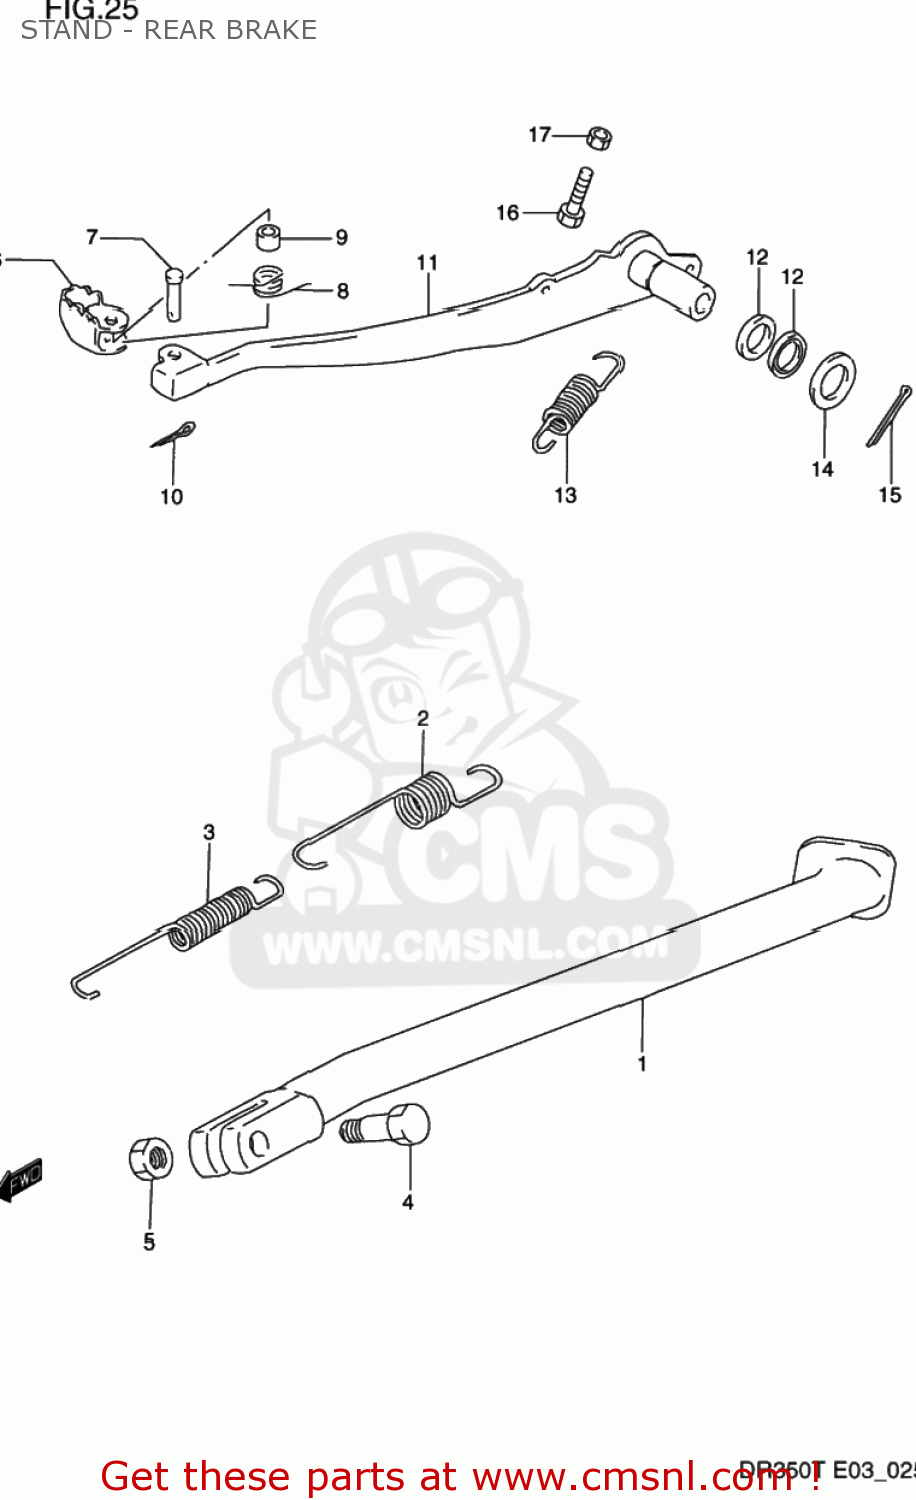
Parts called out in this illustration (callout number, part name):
1	STAND,SIDE
2	SPRING
3	SPRING
4	BOLT(10X30)
5	NUT
6	PEDAL,BRAKE
7	PIN
8	SPRING
9	SPACER(9.2X9X6.5)
10	PIN
11	ARM,BRAKE PEDAL
12	SEAL,OIL(15X21X3)
13	SPRING
14	WASHER(15.5X26X2.3)
15	COTTER PIN
16	BOLT(6X23)
17	NUT
